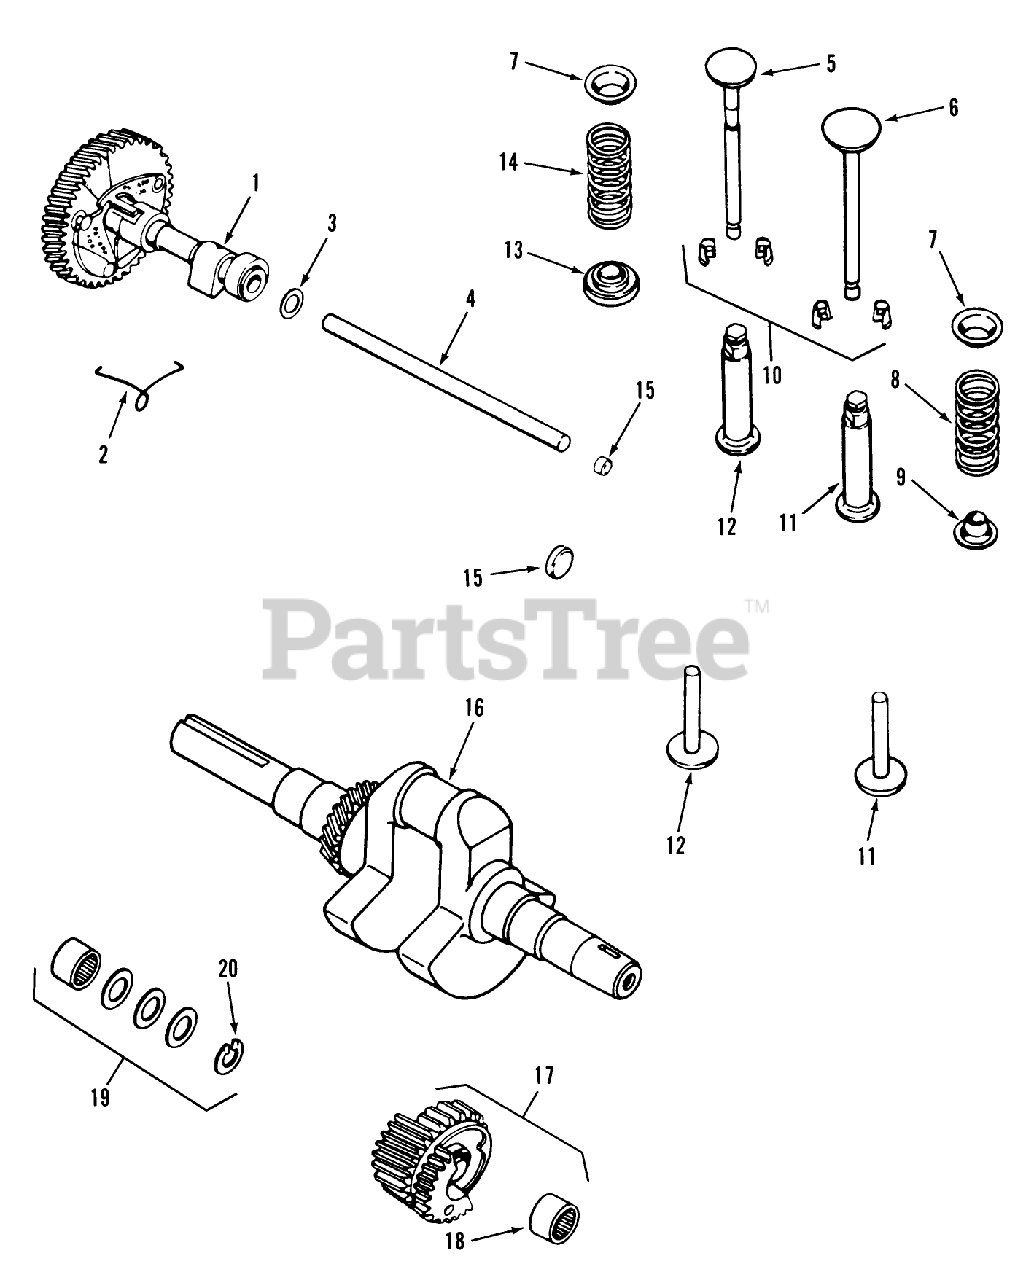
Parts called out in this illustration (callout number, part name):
1	KOHLER 41-010-07
2	KOHLER 47-089-01
3	KOHLER 230293
4	KOHLER 41-380-03
5	KOHLER 230027
6	KOHLER 230008
7	KOHLER 235011
8	KOHLER 230010
9	KOHLER 230011
10	KOHLER 41-755-10
11	KOHLER 230013
12	KOHLER 232777
13	KOHLER 52-413-01
14	KOHLER 230168
15	KOHLER 52-139-09
16	KOHLER 231767
17	KOHLER 45-043-03
18	KOHLER 47-030-01
19	KOHLER 47-755-01
20	KOHLER X-269-34
